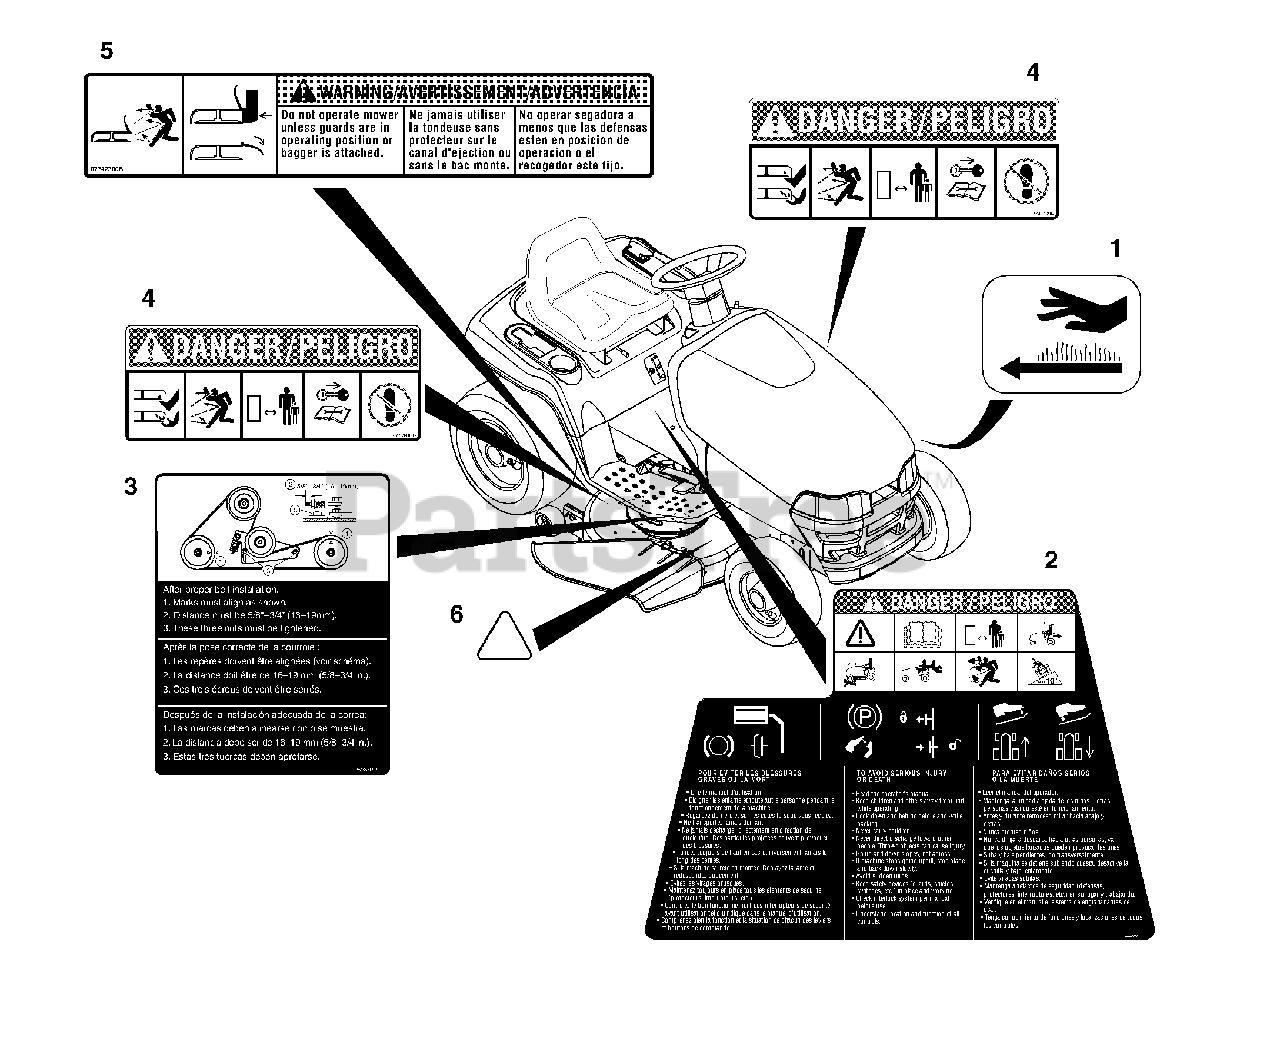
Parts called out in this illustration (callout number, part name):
1	DECAL- HOT SURFACE SYMB.
2	DECAL-OPER INST YT
3	DECAL-BELT DIAGRAM 42"
4	DECAL, MOWER PAN DANGER
5	DECAL, WARNING
6	DECAL, BLADE ALIGNMENT
